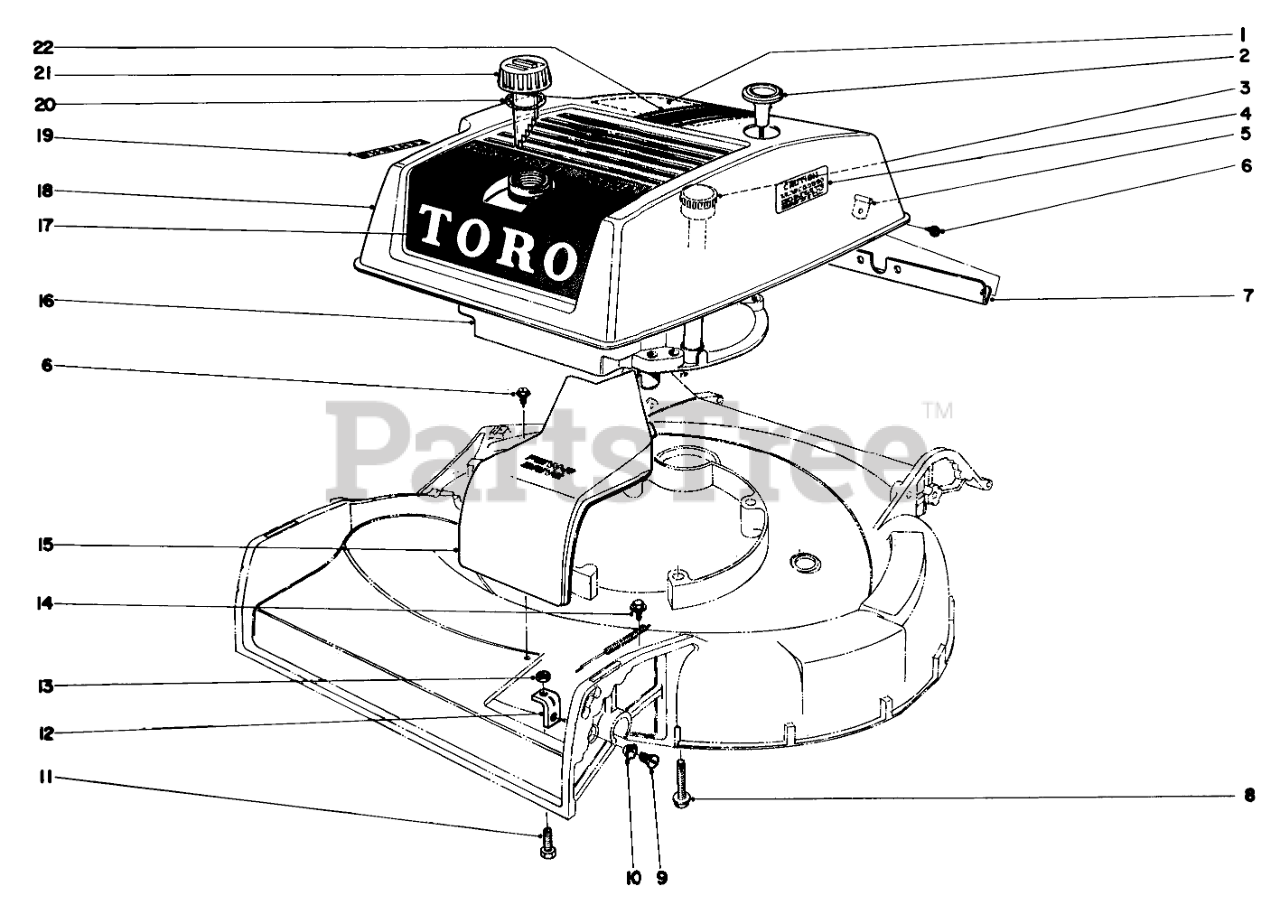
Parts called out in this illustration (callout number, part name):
1	Decal-Maintenance
2	Handle, Rope
3	Dip Stick
4	Decal
5	Hinge
6	SCREW-HWHTF
7	Shroud Bracket
8	3/8-16 X 2-3/4 CAPSCR
9	5/16-18X5/8 FLT HD MS
10	Lockwasher
11	SCREW
12	ADJ BRACKET
13	NUT-JAM
14	SCREW-HHF
15	Belt Drive Cover
16	Engine
17	Decal
18	Shroud
19	Decal, Air Cleaner
20	Gasket
21	Gas Cap
22	Decal
